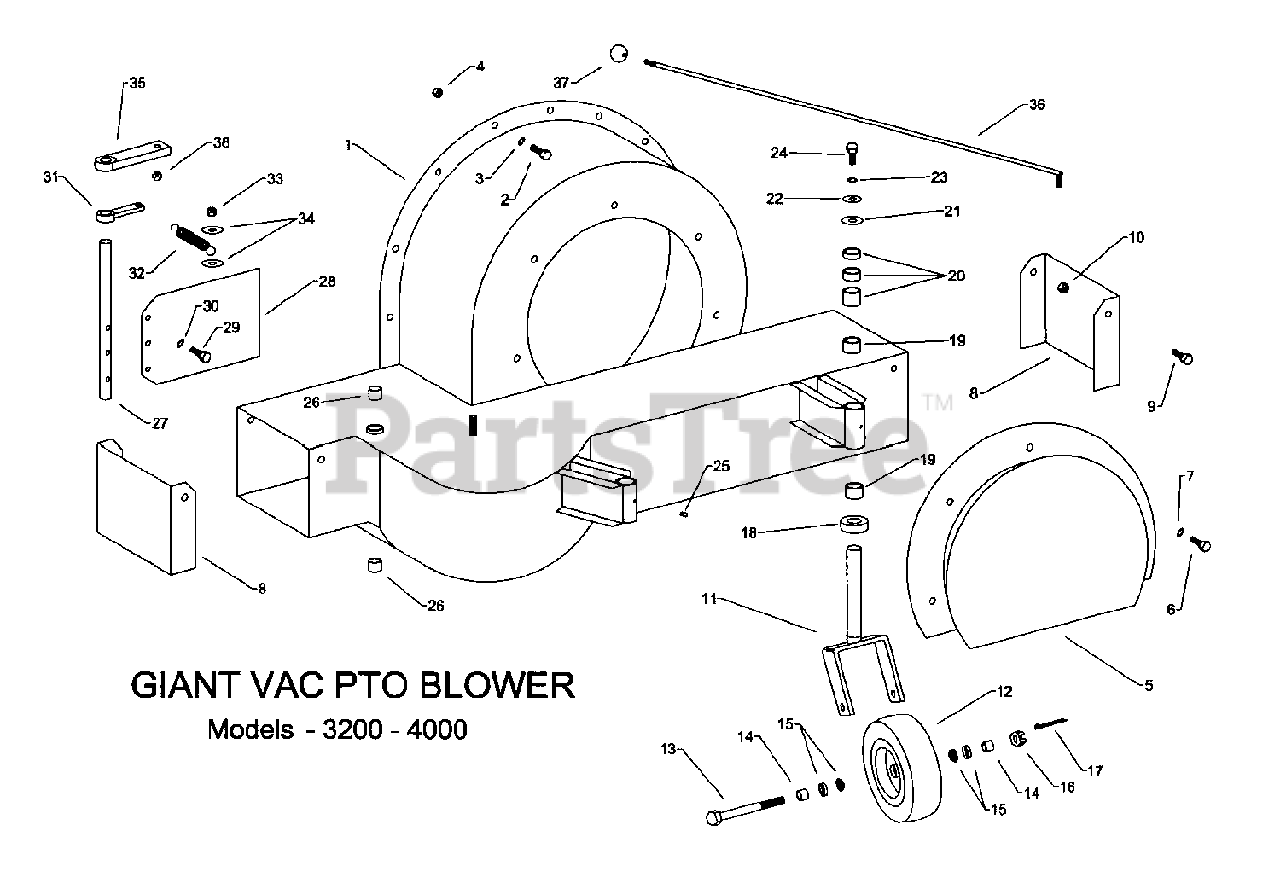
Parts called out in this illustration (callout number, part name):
1	Blower housing
2	1/2 x 1-1/4 hex bolt
2	½ x 1-1/2 hex bolt (shaft frame bottom cover)
3	1/2 lockwasher
4	1/2 hex nut
5	Intake baffle
6	3/8 x 1 hex bolt
7	3/8 lockwasher
8	Deflector – left hand discharge
8	Deflector – right hand discharge
8	Deflector - typical
9	3/8 x 1 hex bolt
10	3/8 lock nut
11	Caster horn
12	Caster wheel - 410-350-6
13	3/4 x 7 axle bolt
14	Axle spacer
15	Wheel bearing & seal
16	3/4-25 axle castle nut
17	Axle nut cotter pin
18	Caster horn thrust bearing 1-1/4
19	Sleeve bushing 1-1/4 ID
20	Caster horn spacer set (2,1,1/2)
21	5/8 flatwasher
22	1/2 flatwasher
23	1/2 lockwasher
24	1/2 x 1-1/4 hex bolt
25	Caster horn grease fitting
26	Sleeve bushing 1-1/4 ID
27	Inner deflector door rod
28	Inner deflector door
29	3/8 x ¾ hex bolt
30	3/8 lockwasher
31	Spring arm holder
32	Spring
33	1/2 lock nut
34	1/2 flatwasher
35	Deflector rod upper arm
36	Control rod
37	Control rod knob - 3/8
38	1/2 lock nut
